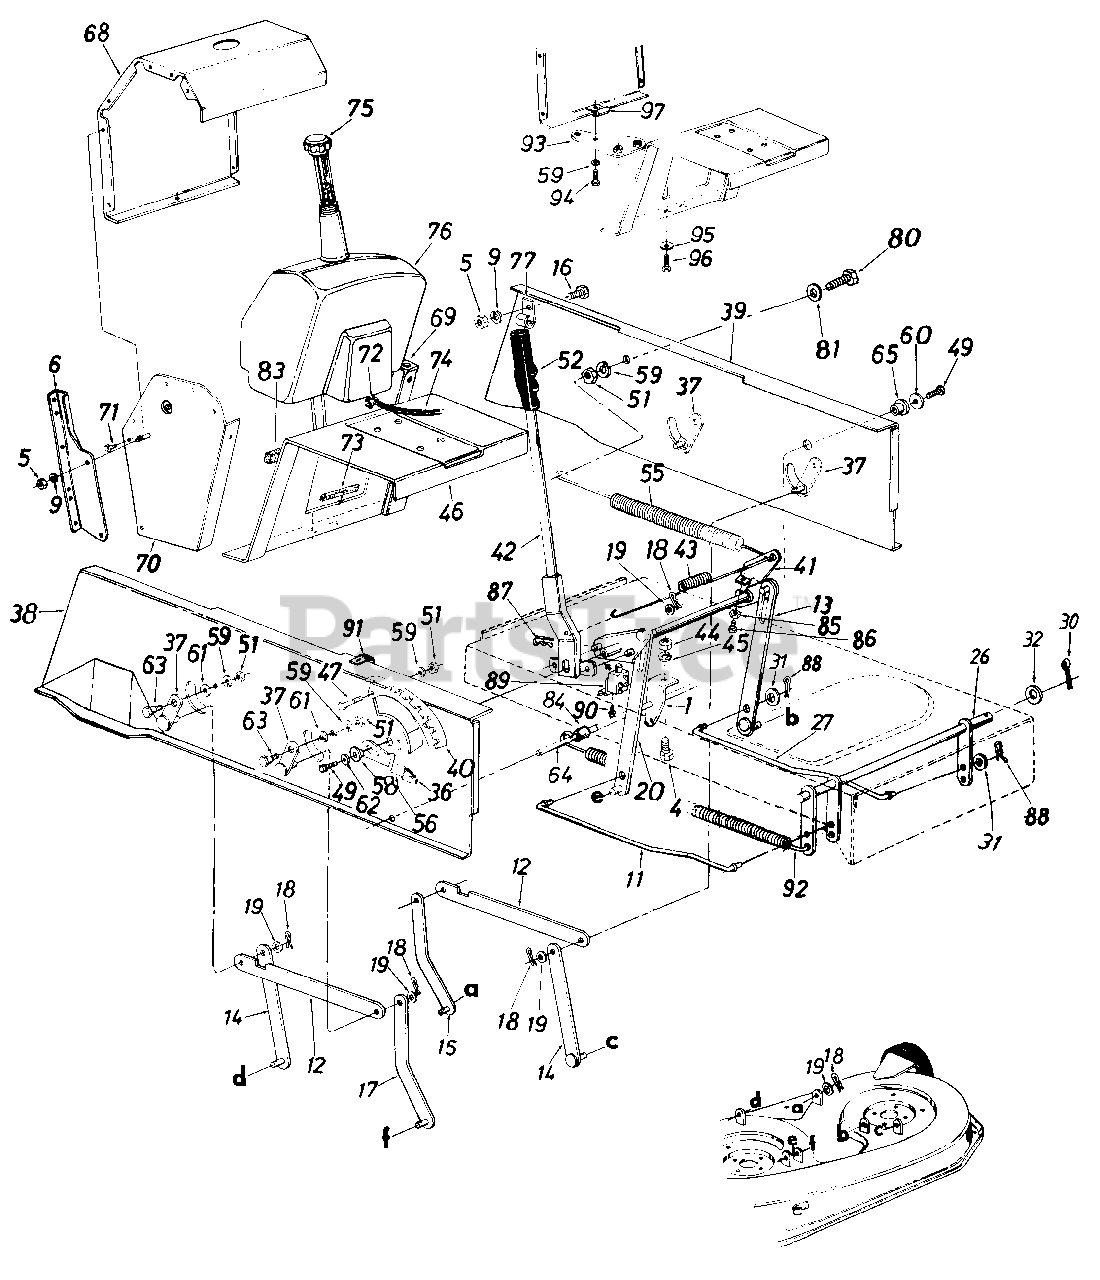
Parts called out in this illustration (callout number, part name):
1	Spring Hanger Bracket
4	Hex Bolt 1/4-20 x .62n Lg.
5	Hex Nut 5/16-18 Thd.
6	Mounting Bracket-R.H.
9	L-Wash. 5/16" l.D.
11	Stabilizer Rod
12	Connecting Rod 3/16 x 1 x 12.5
13	Deck Lift Link Ass'y.
14	Deck Hanger Link Ass'y.
17	Deck Hanger Link Ass'y.-
18	Inter. Cotter Pin 1/2" Dia.
19	Fl-Wash. .531 I.D. x .93" O.D.
20	Deck Lift Link Ass'y.
26	Stabilizer Shaft Ass'y.
27	Stabilizer Rod
30	Cotter Pin 1/8" Dia. x 1.25" Lg.
31	Fl-Wash .385" 1 D 0 x .620" O.D.
32	Fl-Wash. 635" l.D. x 1.12" O.D.
36	Knob-Height Adj.
37	Pivot Link Ass'y.
38	Side Panel Upper Frame-R.H.
39	Side Panel Upper Frame-L.H.
40	Index Brkt.
41	Lift Shaft Ass'y.
42	Lift Handle Brkt. Ass'y.
44	Hex Nut 1/4-20 Thd.
45	L-Wash. 1/4" l.D.
46	Hitch Plate
47	Hex Bolt 5/16-18 x 75n Lg.
49	Hex Wash. TT-Tap Scr. 5/16-1 8 x .62" Lg.
51	Hex Nut 5/16-18 Thd.
52	Grip
55	Ext. Spring .99" Dia. x 11.00" Lg.
56	Deck Lift-Down Stop
58	Flange Brg. 630" l.D.
59	L-Wash. 5/16" l.D.
60	Fl-Wash. .344" I.D. x 1.125" O.D.
61	Fl-Wash. 344" l.D. x .62" O.D. x .063
62	Fl-Wash. .344" I.D. x 1.125" O.D.
63	Shld. Bolt .437" Dia. x .180
64	Running Board Rod
65	Flange Brg. .632" I.D.
68	Gas Tank Housing-Main Panel
71	Truss. Mach. B-Tap Scr. #10 x .50" Lg.
72	Hose Clamp-.406" Dia.
73	Trim Strip-5n Lg.
74	Gas Line-44" Lg.
75	Gas Tank Cap
80	Hex Bolt 5/16-18 x 1.50" Lg.
81	Fl-Wash. .344n l.D. x .875" O.D.
83	Foam Strip 3/8" x 1-1/8" x 1/2" Lg.
84	Spacer .523" I.D. x 640n O.D. x 1.95 ' Lg.
85	Hex Jam Nut 5/16-18 (Grade 5)
86	Hex Wash. Hd. Tap Scr. 5/1 6-1 8 x 1 " Lg.
87	Internal Cotter Pin 3/8" Dia.
88	Cotter Pin 3/32" Dia.
89	Safety Switch
90	Truss Mach. Scr. #10 x .5" Lg.
92	Ext. Spring 13.25" Lg.
93	Hitch Bar Ass'y.
94	Hex Bolt 5/16-18 x 1.0" Lg. (Grade 5 )
95	Bell-Wash. . 385" 1.0" x .88"
96	Hex Wash. Tap-Scr. 3/8-16 x .75" Lg.
97	U-Nut 5/16-18 Thd.
